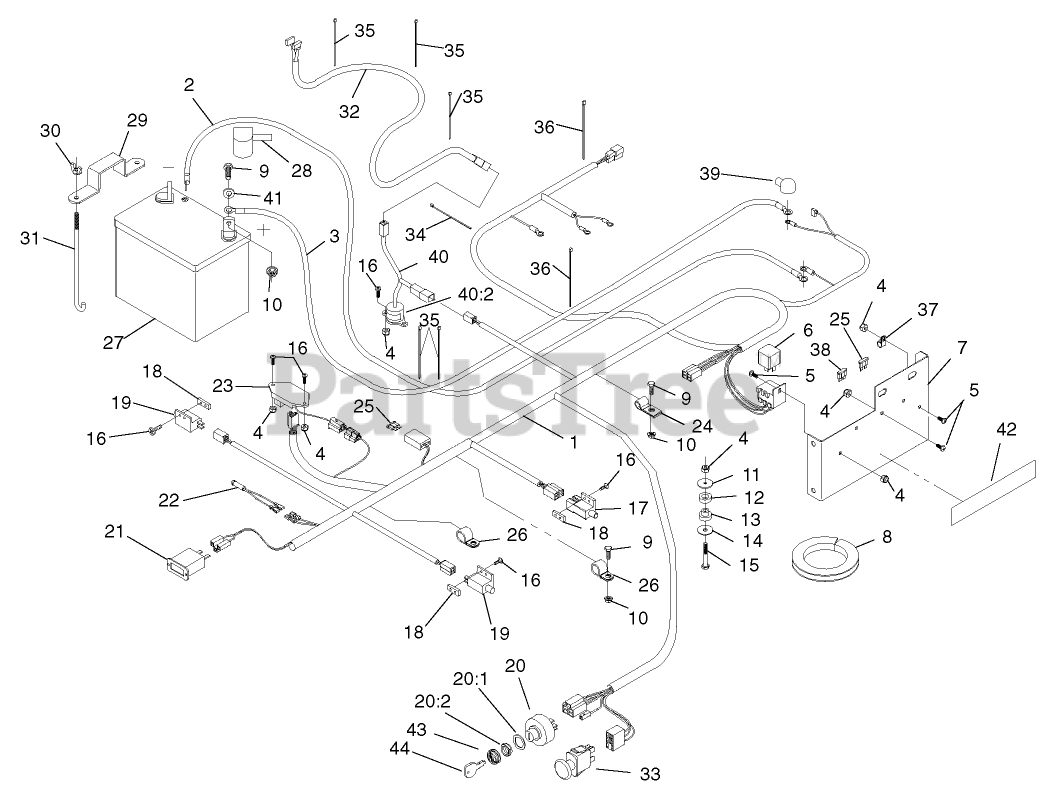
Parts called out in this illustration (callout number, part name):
1	HARNESS-WIRE
2	WIRE-GROUND
3	WIRE-BATTERY, POSITIVE
4	NUT-LOCK, NI
7	PANEL-FUSES & RELAYS
8	TRIMLOCK
9	SCREW-HH
10	NUT-HF
11	WASHER
12	RINGMOUNT-VIBRATION
13	Mount-Bushing,Vibration
14	WASHER
16	SCREW-PPH
17	SWITCH
18	PLATE-TAPPED
19	SWITCH-OPEN, NORMALLY
20	Key Switch ASM
20:1	WASHER-TOOTH, INTERNAL
20:2	NUT-HH
21	METER-HOUR
22	INDICATOR-LED, RED
23	MODULE-DELAY, SEAT
24	CLIP-LOOM
25	FUSE-BLADE TYPE, 20 AMP
27	BATTERY
28	INSULATOR-BATTERY
29	STRAP-HOLDDOWN
30	WINGNUT
31	BOLT-HOLDDOWN
32	HARNESS-WIRING, SEAT
33	SWITCH-DELTA
34	TIE-CABLE
35	TIE-PLASTIC
36	TIE-PLASTIC
37	CLIP-LOOM
38	FUSE-BLADE TYPE, 10 AMP
39	INSULATOR-SOLENOID
40	TILT SWITCH ASM
40:2	DECAL-SWITCH, MERCURY
41	WASHER-FLAT
42	Decal-Fuse/Relay
43	SEAL-SWITCH, IGNITION
44	KEY-IGNITION
